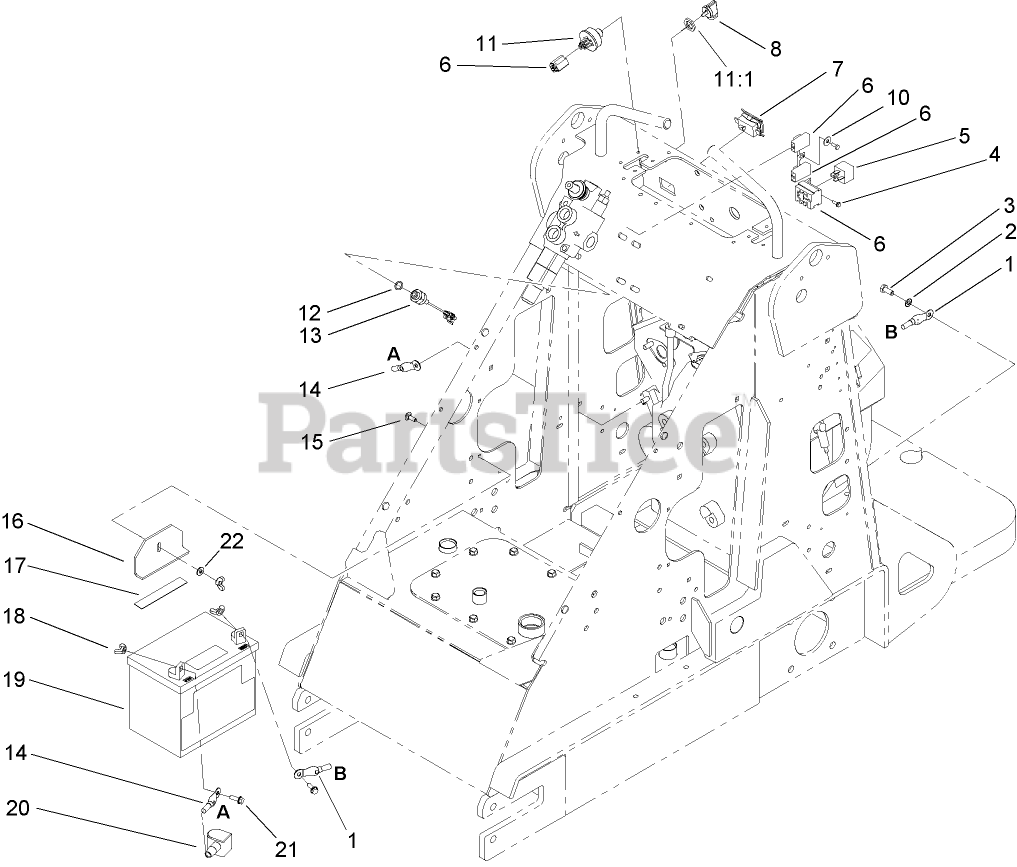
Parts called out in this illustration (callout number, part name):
1	CABLE-BLACK
2	WASHER-LOCK
3	SCREW-HH
4	SCREW-HWHTF
5	RELAY
6	HARNESS-ELECTRICAL
7	METER-HOUR
8	KEY-IGNITION
10	WASHER-PLAIN
11	KEY SWITCH ASM
12	O-RING
13	SWITCH-BALL
14	WIRE-21 INCH
15	SCREW-CARR
16	CLAMP-BATTERY
17	PAD-FOOTREST
18	NUT-WING
19	BATTERY-DRY
20	BOOT-TERMINAL, RED
21	SCREW-HHF
22	WASHER-FLAT
